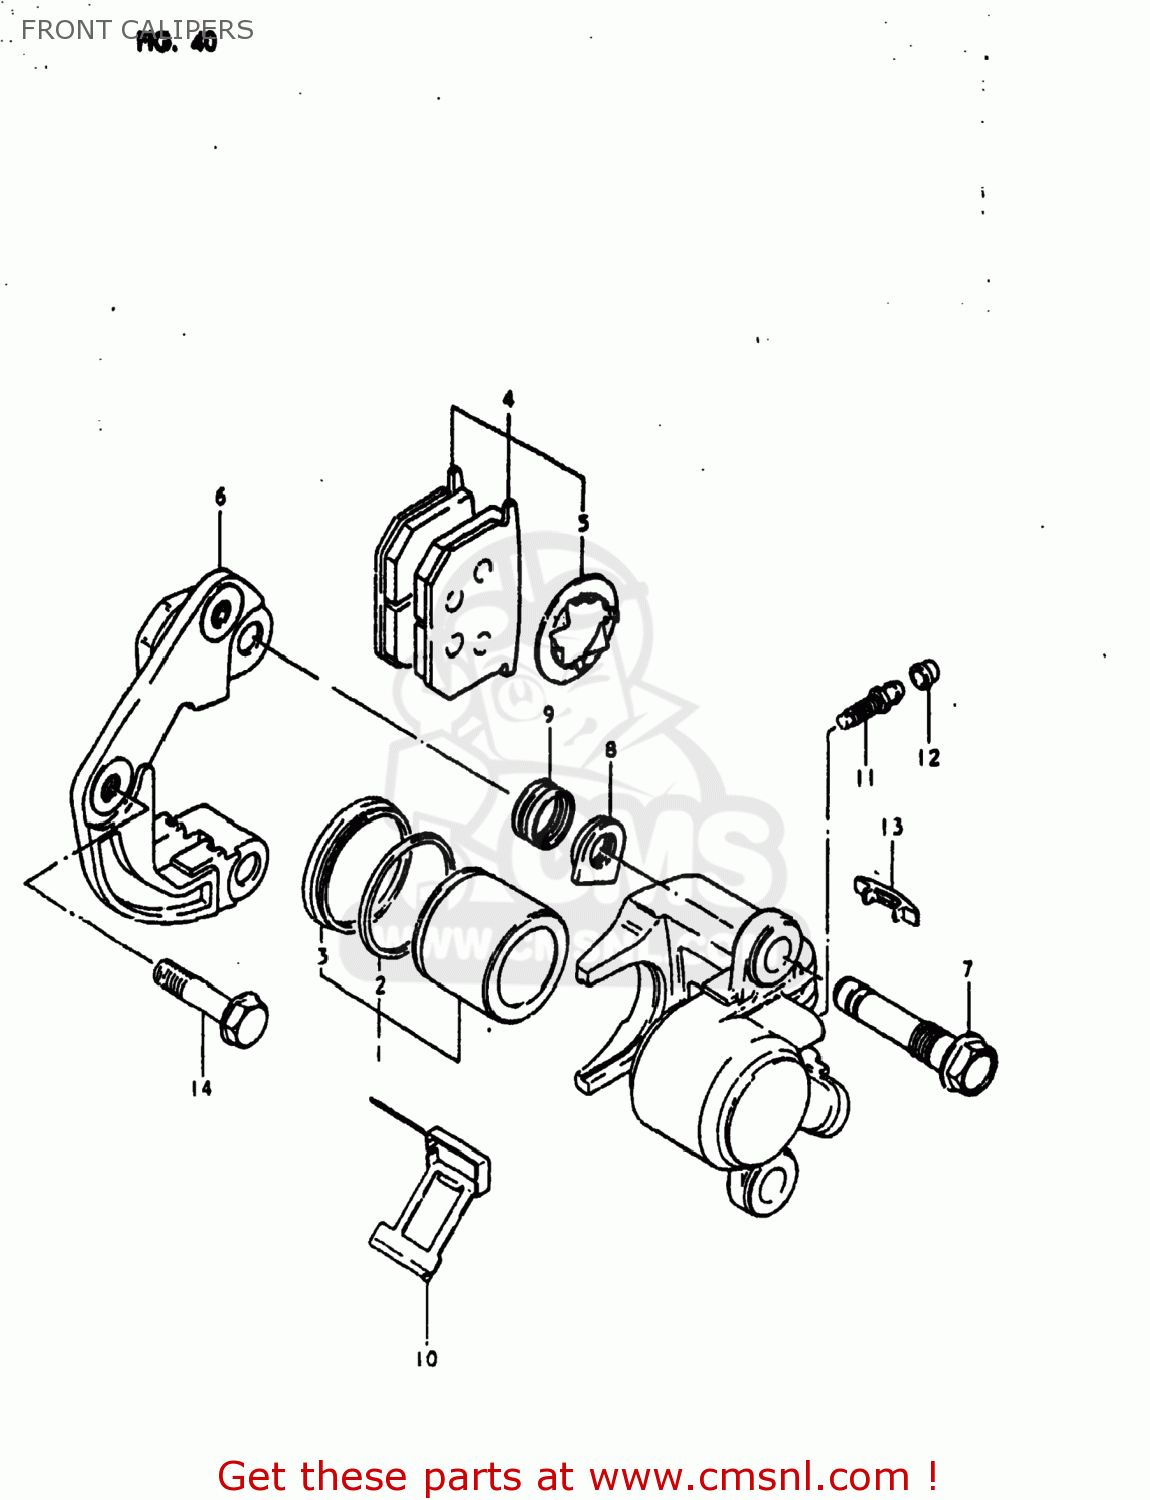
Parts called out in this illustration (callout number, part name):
0	CALIPER ASSEMBLY,LEFT
1	PISTON SET
2	SEAL,PISTON
3	BOOT,PISTON
4	PAD & SHIM SET (MCA)
5	SHIM,PAD
6	BRACKET
7	AXLE,CALIPER
8	NUT,CALIPER AXLE
9	BOOT
10	SPRING
11	BREATHER
12	CAP,BLEEDER PL
13	COVER,INDICATOR
14	BOLT(10X37)
